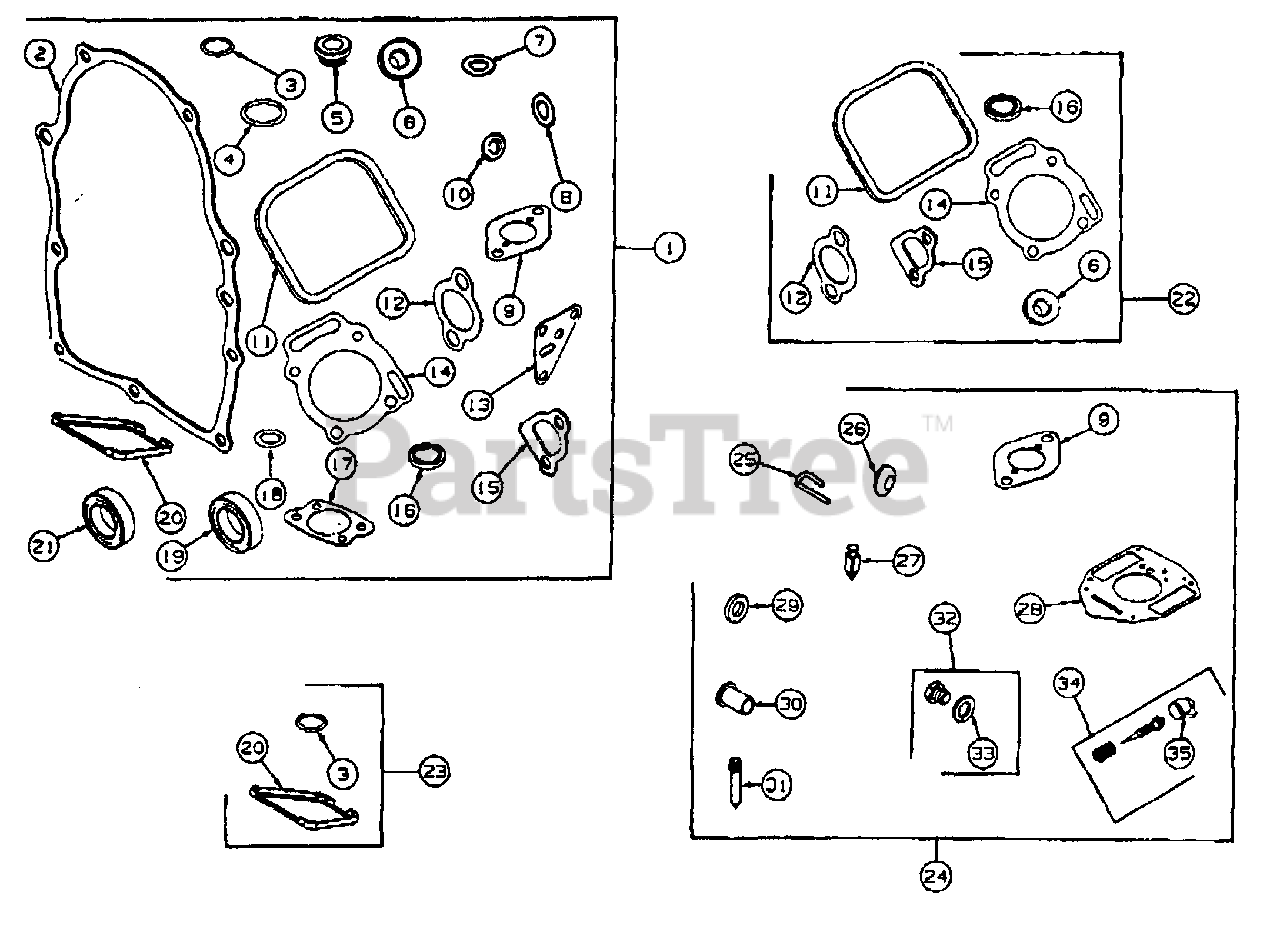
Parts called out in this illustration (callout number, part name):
1	Gasket Set
2	Gasket, Crankcase
3	Seal, Breather Tube
4	Seal, O-Ring
5	Seal, Fill Tube
6	Washer
7	Seal, O-Ring
8	Seal, O-Ring
9	Gasket, Intake
10	Seal, O-Ring
11	Gasket, Valve Cover
12	Gasket, Exhaust
13	Gasket, Valve Cover
14	Gasket, Cylinder Head
15	Gasket, Intake
16	Seal, Fill Plug
17	Gasket, Air Cleaner
18	Seal, Governor Shaft
19	Seal, Oil
20	Gasket, Breather
21	Seal, Oil
22	Gasket Set, Valve
23	Gasket Set, Breather
24	Overhaul Kit, Carburetor
25	Pin, Float Hinge
26	Plug, Welch
27	Valve, Fuel Inlet
28	Gasket, Carburetor Body
29	Collar, Throttle
30	Collar, Choke
31	Nozzle, Carburetor
34	Valve, Idle, Adjust
35	Cap, Limiter
